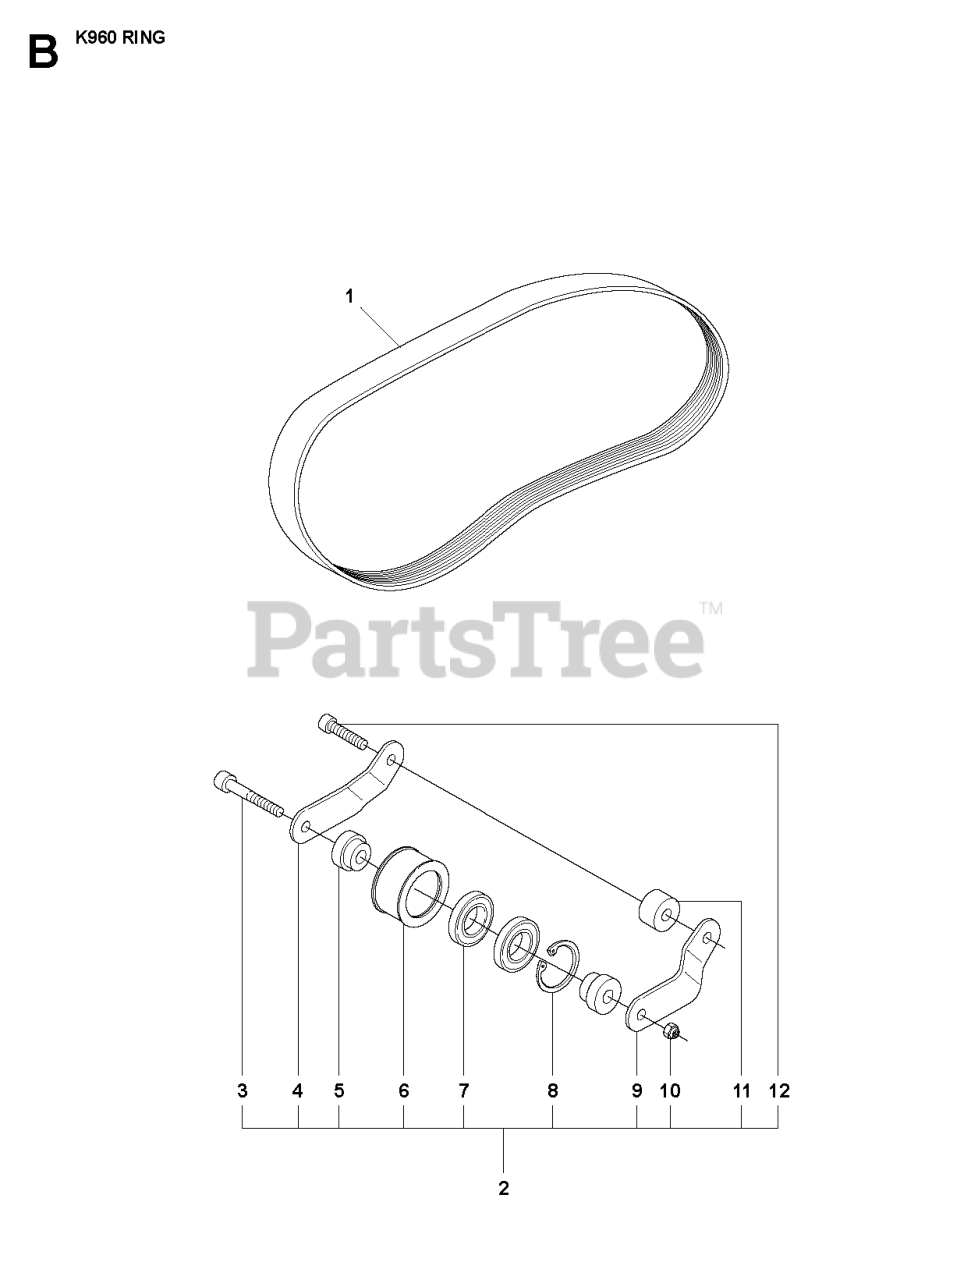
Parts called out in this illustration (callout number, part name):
3	SCREW ITXSCM M6X37/25 T27 12.
7	BEARING
8	RETAINING RING SGH 28
10	LOCKNUT M6
